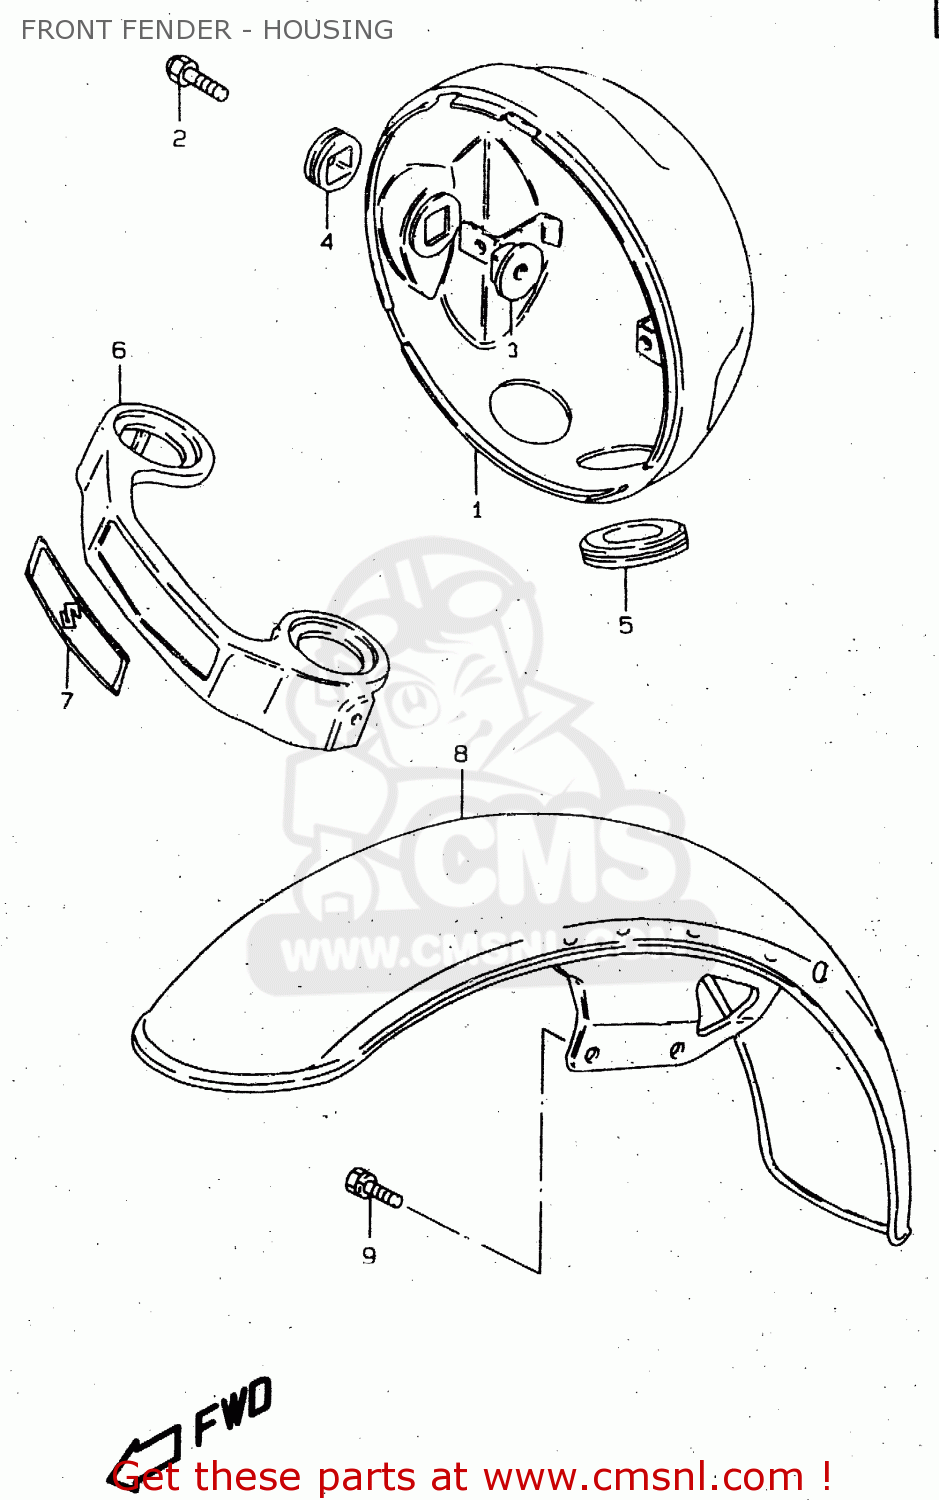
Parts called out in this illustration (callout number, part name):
1	HOUSING,HEADLAMP
2	BOLT
3	SPACER,HEADLAMP HOUSING
4	CUSHION,HEADLAMP HOUSING
5	GROMMET,HEADLAMP HOUSING
6	COVER,FR FORK
7	EMBLEM,FR FORK COVER
8	FENDER,FR
9	BOLT, UPPER
